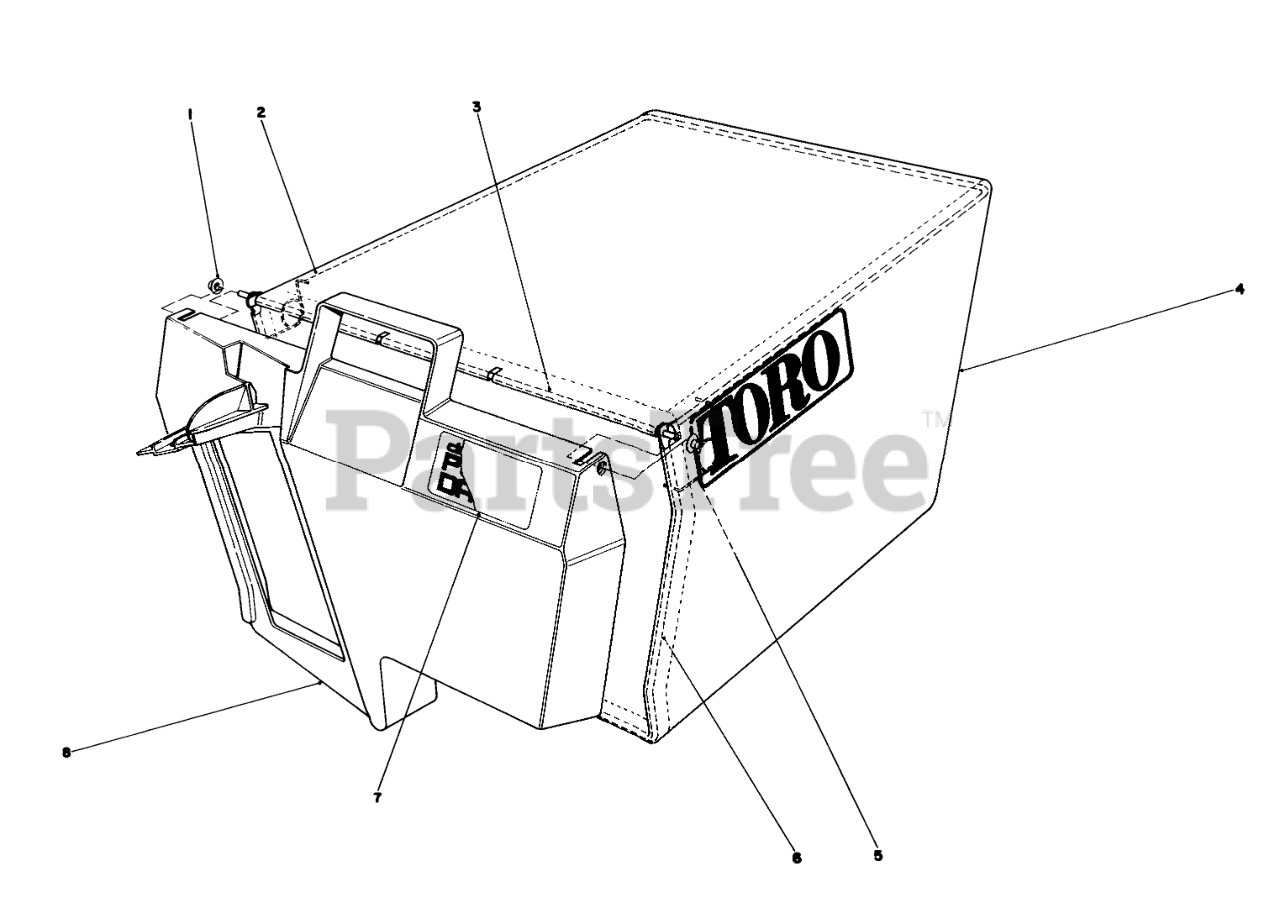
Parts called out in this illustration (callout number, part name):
1	NUT-PUSH
2	FRAME-BAG, UPPER
3	HingeBag Door
4	Bag
5	SPRING
6	FRAME-BAG
7	BAG DOOR DECAL
8	DOOR-BAG
